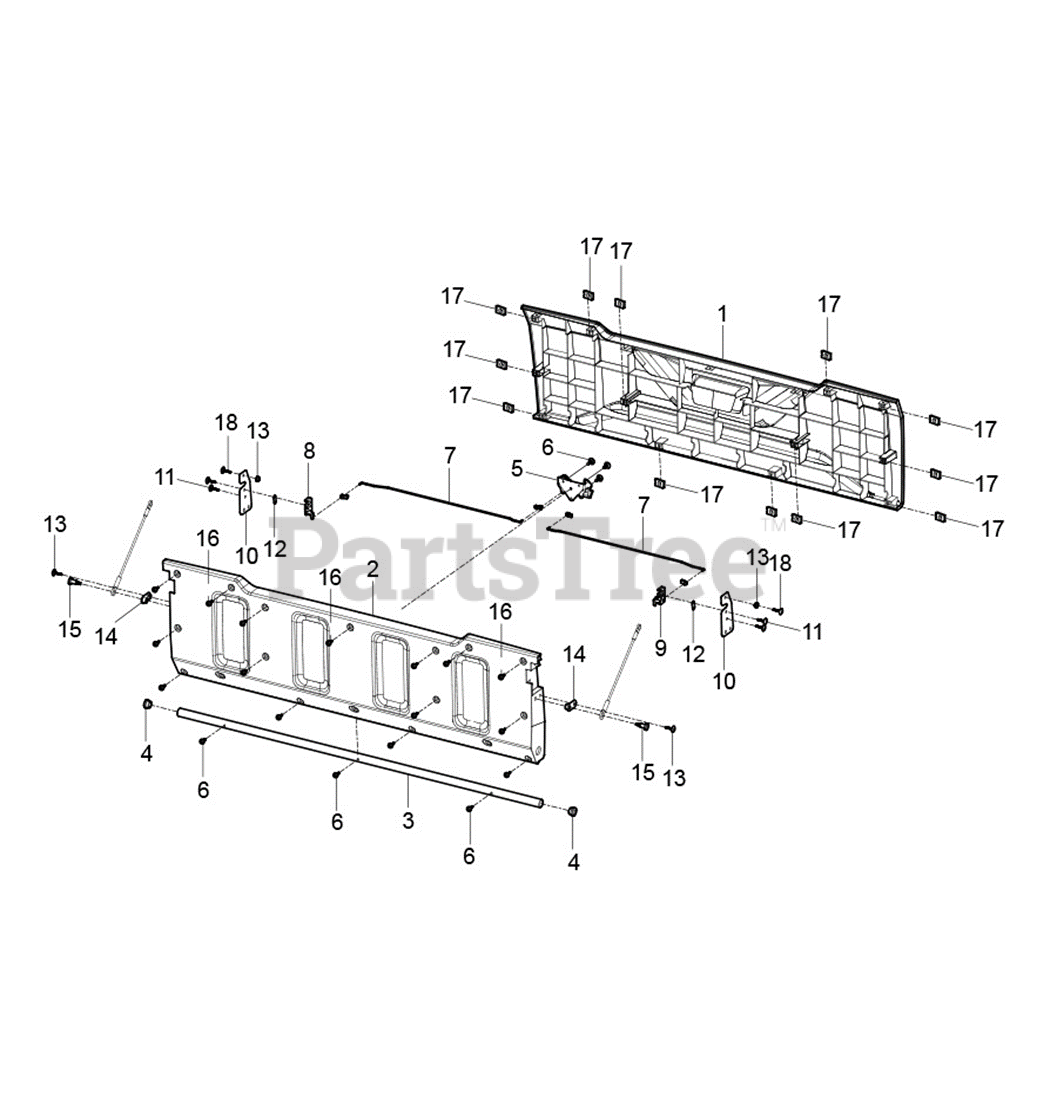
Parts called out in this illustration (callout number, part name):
1	CARGO BED DOOR - RED
1	CARGO BED DOOR YELLOW
1	CARGO BED DOOR BLUE
1	CARGO BED DOOR BLACK
1	CARGO BED DOOR G2 CAMO
2	CARGO BED DOOR INSIDE PANEL
3	CARGO BED DOOR HINGE TUBE
4	BUSHING PLASTIC 10.5X18
5	CARGO BED LOCK ASSEMBLY
6	SCREW M6X12
7	ROD - CARGO BED DOOR LOCK
8	CARGO BED DOOR LOCK KIT RH
9	CARGO BED LOCK KIT LH
10	DOOR LOCKING PLATE
11	SCREW M6X16
12	DOOR LOCK ADJUSTMENT GASKET
13	HEX FLANG NUT M6
14	DOOR LOCK STRAP PLATED
15	BOLT HEX SOCKET SHLD M8X18-1
16	SOCKET HEX FLAT HEAD BOLT M6X16
17	CLAMP NUT M6X6
18	SCREW M6X20 LG PLT HD
